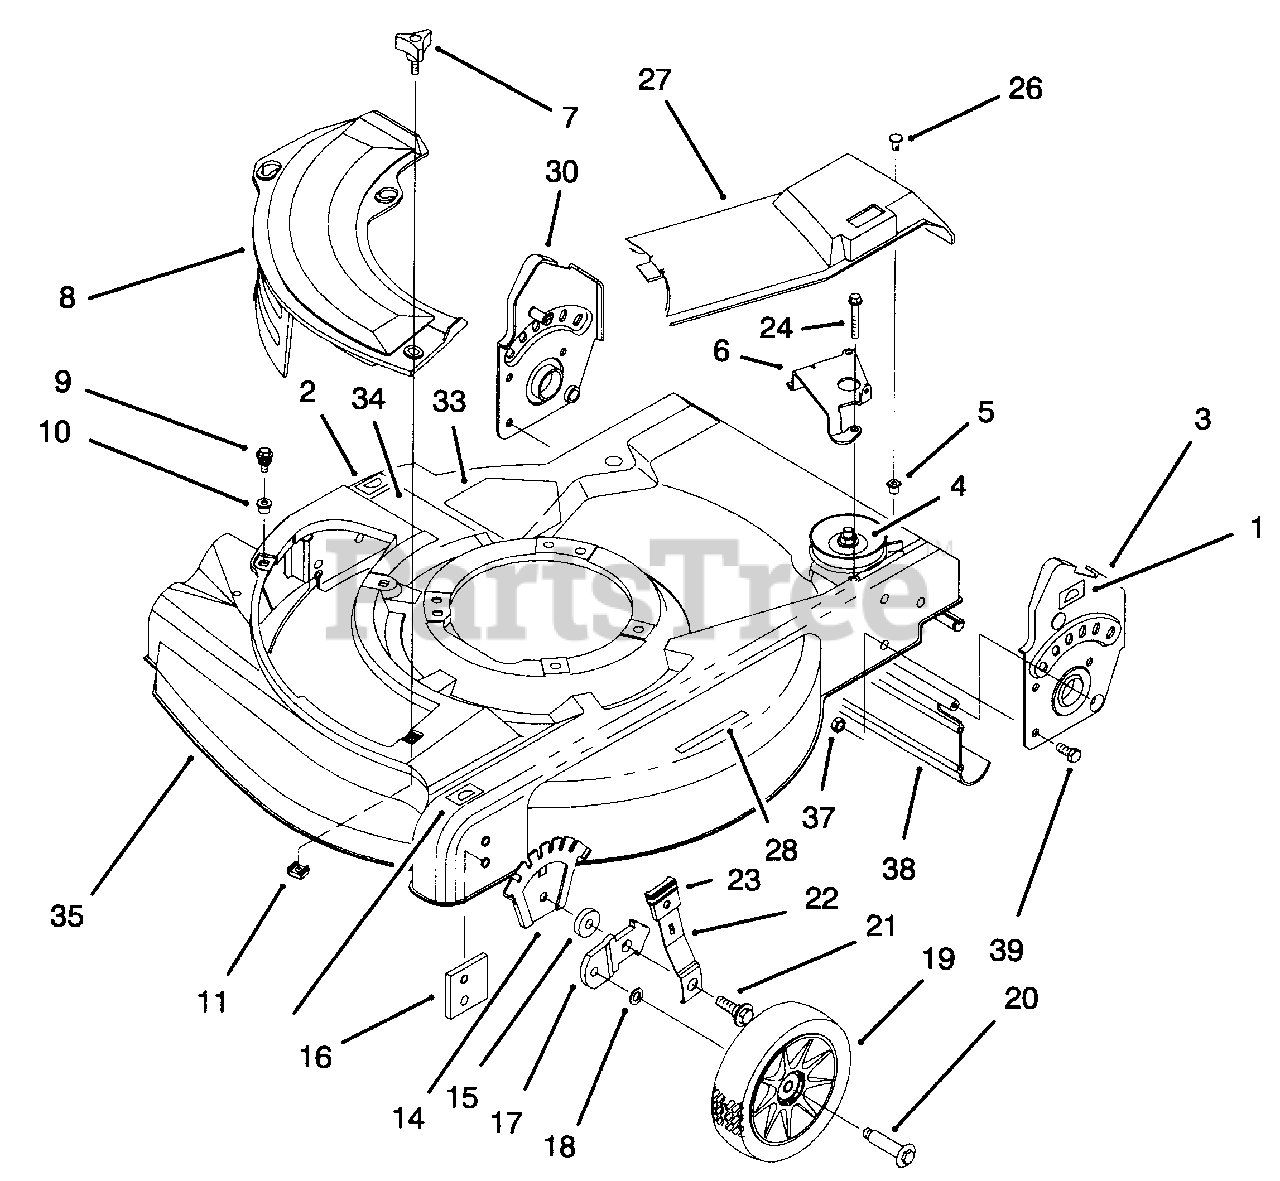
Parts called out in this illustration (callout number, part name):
1	Decal-H.O.C.
2	Decal-H.O.C.
3	Bracket-Handle L.H.
4	Gear Case Assembly
5	Grommet
6	Guide-Transmission
7	Knob-Cover Plate
8	Plate-Mulch 21"
9	Screw-Sems Thr'd Form.
10	Grommet-Plastic
11	Nut-Cage
14	Plate-Height Adjust
16	Plate-Baffle
17	Bracket-Wheel Height Adj.
19	Wheel & Tire Assembly-6"
20	Bolt-Shoulder
21	Bolt-Shoulder
22	Spring Arm-Front
23	Knob-Height Adjust
24	Screw-Hex Hd. Cap
26	Screw-Phillip Hd.
27	Cover-Drive
28	Decal-Warning
30	Bracket-Handle R.H.
33	Decal-Danger
34	Decal-Discharge
35	Housing Assembly (Incl. Ref. #5, 10, 11, 28, 33, & 34)
37	Nut-Hex Lock
38	Shield-Trailing
39	Screw-Hex Hd. Cap
